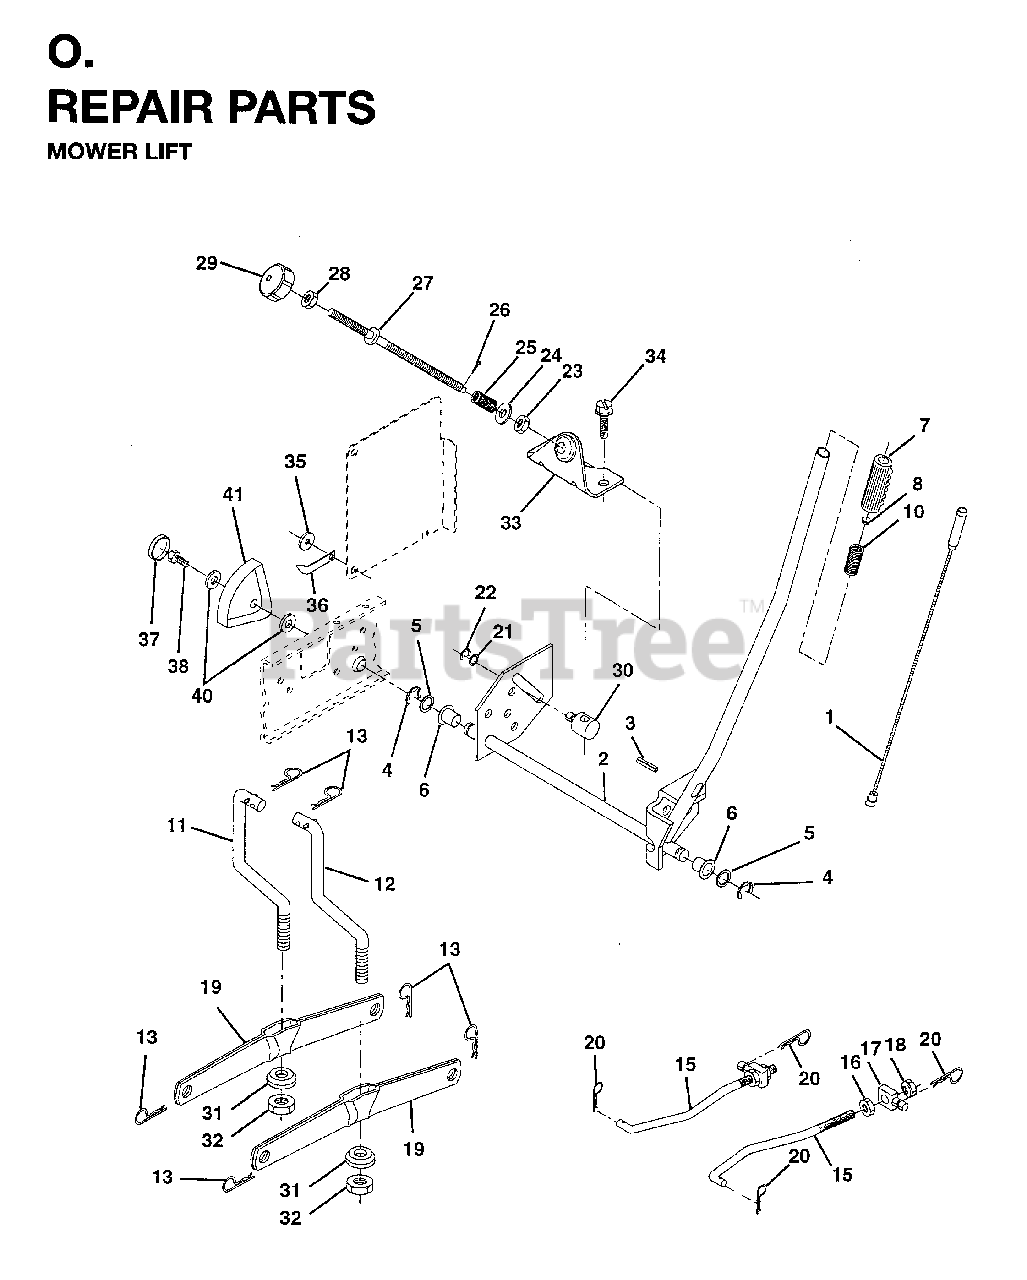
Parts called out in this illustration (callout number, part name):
1	WIRE, INNER HANDLE
2	SHAFT ARM LIFT RH
3	PIN GROOVE
4	RETAINING RING LT
6	BEARING.NYLON
7	GRIP HANDLE
8	PLUNGER BUTTON KIT
10	SPRING, COMP T
11	LINK LIFT LH
12	LINK LIFT RH
13	RETAINER SPRING
15	FRONT LINK
16	NUT 1/2 X 13
17	TRUNION
18	NUT
19	ARM.REAR.SUSPENSION
20	SPRING RETAINER
22	KLIP RING
25	SPRING**
26	COTTER PIN
27	ROD ADJ LIFT
28	NUT.HEX.3/8-16UNC
29	KNOB INF 3/8-16
30	TRUNION LT
31	BEARING PIVOT
32	NUT
36	HEIGHT INDICATOR PNTR
37	PLUG,HOLE
38	BOLT
41	HEIGHT INDICATOR
